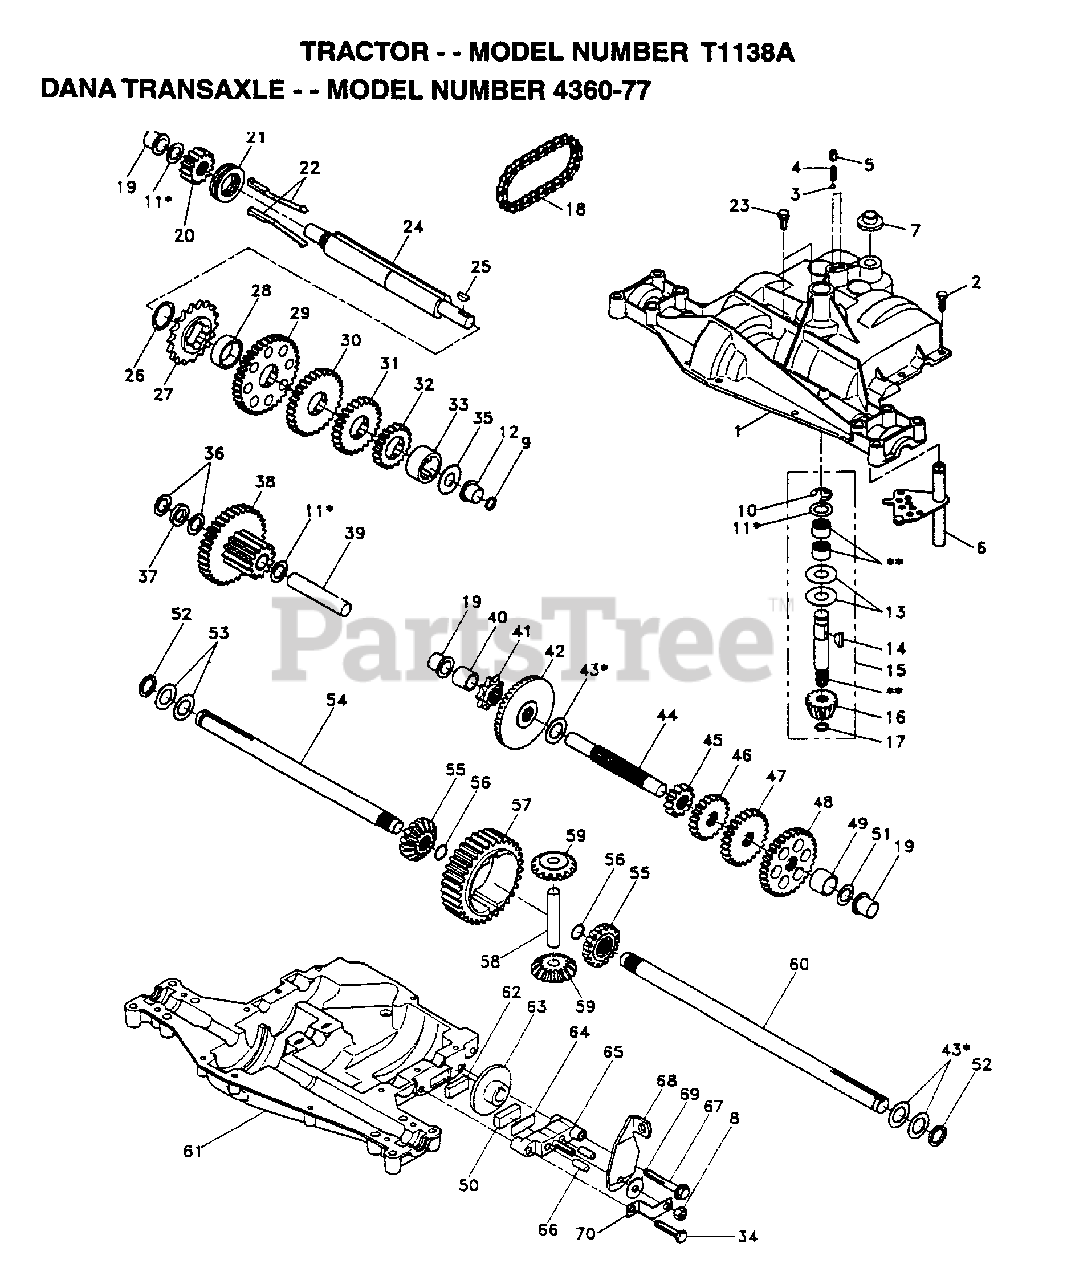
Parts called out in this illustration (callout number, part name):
1	HOUSING UPPER TRN
4	"SPRING, DETENT LT"
5	"SCREW, SET LT"
6	KIT SHIFTER ASM
7	SHIFTER BOOT
8	NUT.LOCK.5/16-24
9	SEAL OIL DANA5416
11	ASM KIT SHIM 4689
13	WASHER T
14	KEY WOODRUFF-DANA
15	AS KIT INPUT SHFT
16	PINION 14T T
17	"RING,RETAINING LT"
18	"CHAIN,24 PTCH LT"
19	BEARING.FLNG.5510
20	GEAR SPUR 14 TTH
21	COLLAR CLUTCH
22	ASM KIT CLTCH KEY
23	SCREW TAP W/SEAL
24	SHAFT INTERM DANA
25	WOODRUFF KEY
26	"RING,RETAINING LT"
27	SPROCKET 18T T
28	SPACER YT
29	GEAR SPUR 37 TTH
31	GEAR 25T LT
32	SPUR GEAR 19T
33	SPACER
34	"SCREW, TAPPING LT"
35	"WASHER, PLAIN LT"
36	WASHER 025
37	SPACER
38	ASSM GEAR COMB
39	SHAFT IDLER
40	SPACER T
41	SPROCKET 9T LT
43	ASM KIT SHIM
44	SHAFT T
45	GEAR SPUR 12 TTH
47	"GEAR, SPUR 25T LT"
48	"GEAR, SPUR 31T LT"
50	PUCK T
51	WASHER 060
52	NEOPRENE WASHER
53	WASHER 031
55	GEAR 15T T
56	"RING,RETAINING LT"
58	SHAFT T
59	GEAR 1ST T
61	HOUSING LOWER TNS
62	PUCK T
63	BRAKE DISC. T
64	SPACER LT
66	PIN T
69	WASHER LT
